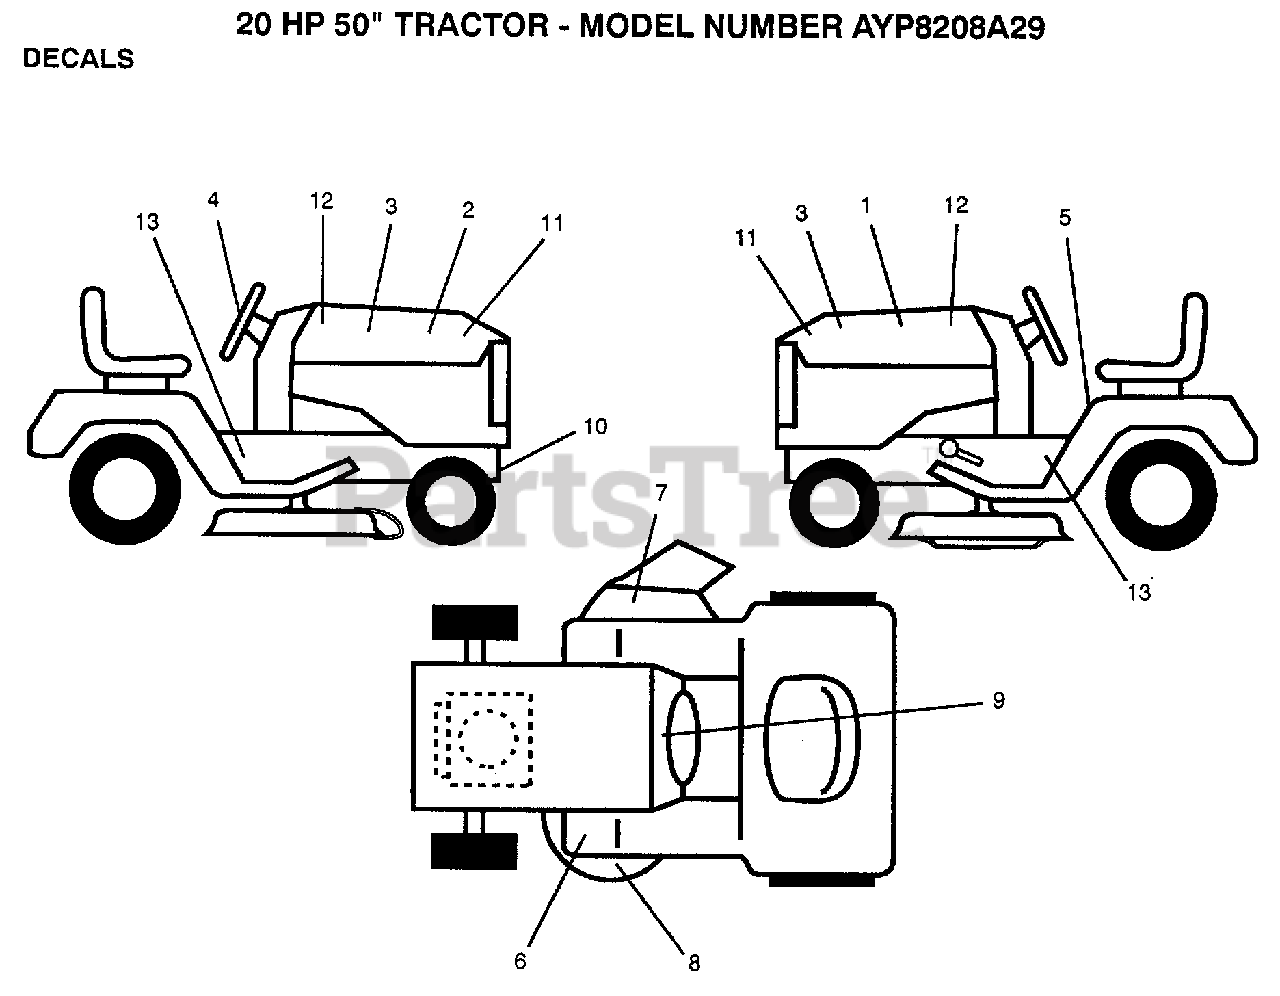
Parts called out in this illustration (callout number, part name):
5	DECAL
7	DECAL WARING
8	DECAL INSTRUCTION CAUTION
